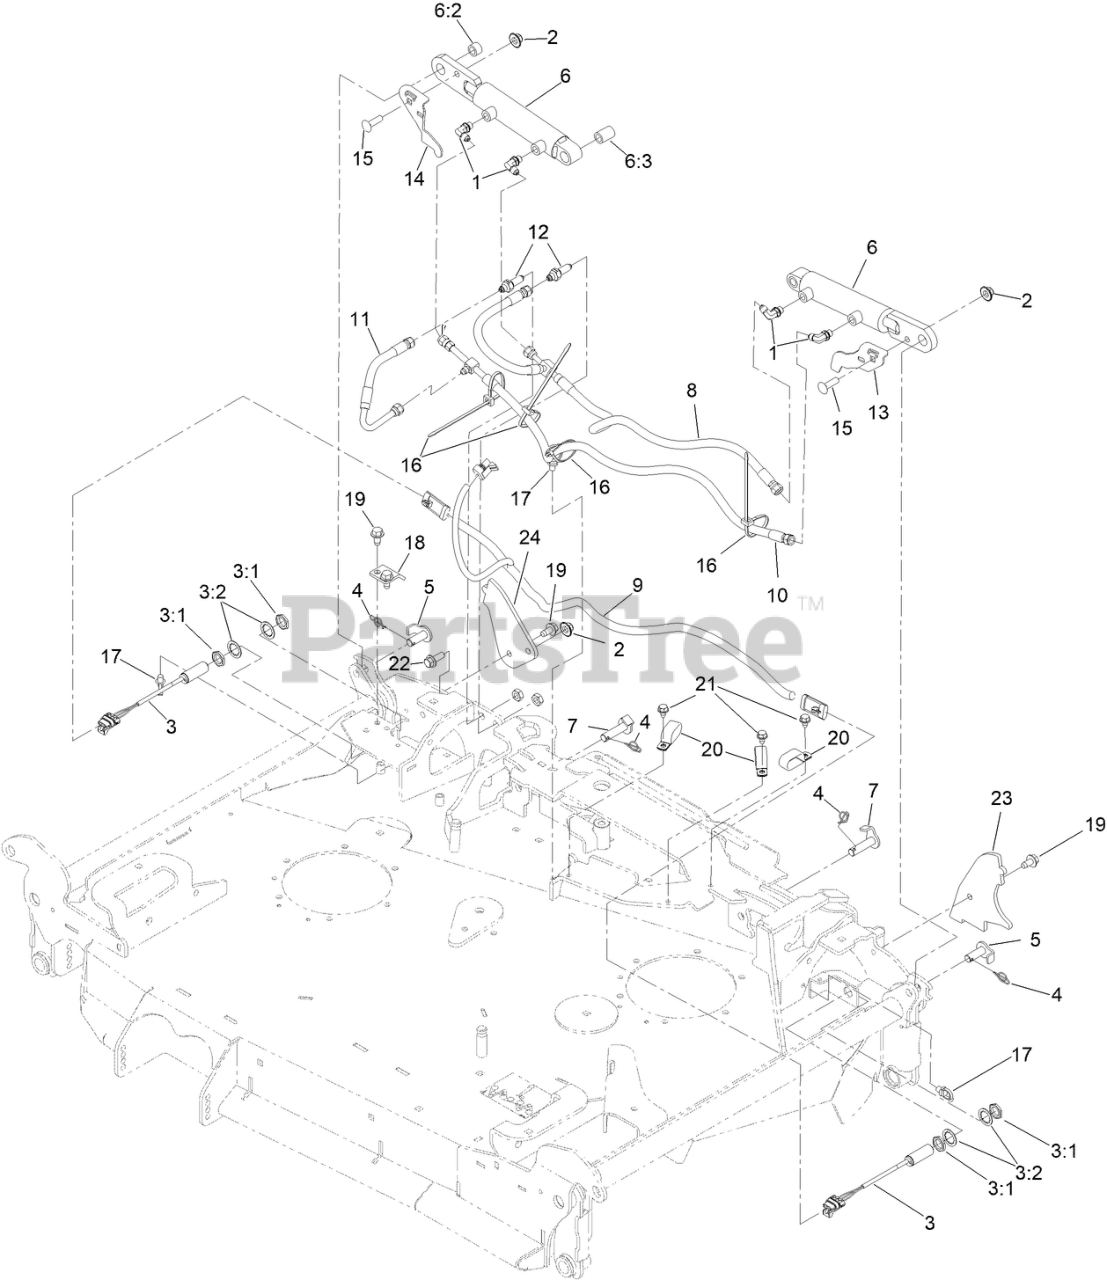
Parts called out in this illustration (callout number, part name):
1	Adapter, 90?
2	NUT-FLANGE, NI
3	PROXIMITY SWITCH ASM
3:1	NUT-HEX
3:2	WASHER-LOCK, INTERNAL TOOTH
4	PIN-COTTER, LOCKING
5	EYE-PIN, CYLINDER
6	DECK FOLD CYLINDER ASM
6:2	BUSHING
6:3	BUSHING
7	PIN-CYLINDER
8	HOSE ASM
9	HARNESS-WIRE
10	HOSE ASM
11	HOSE ASM
12	FITING-STRAIGHT
13	PLATE-PROXIMITY, LH
14	PLATE-PROXIMITY, RH
15	SCREW-CARR
16	TIE-CABLE
17	CLIP-TIE
18	BRACKET-GUARD, SWITCH (RH)
19	SCREW-HWH
21	SCREW
22	SCREW-HHF
23	BRACKET-DECK STOP, LH
24	BRACKET-DECK STOP, RH
